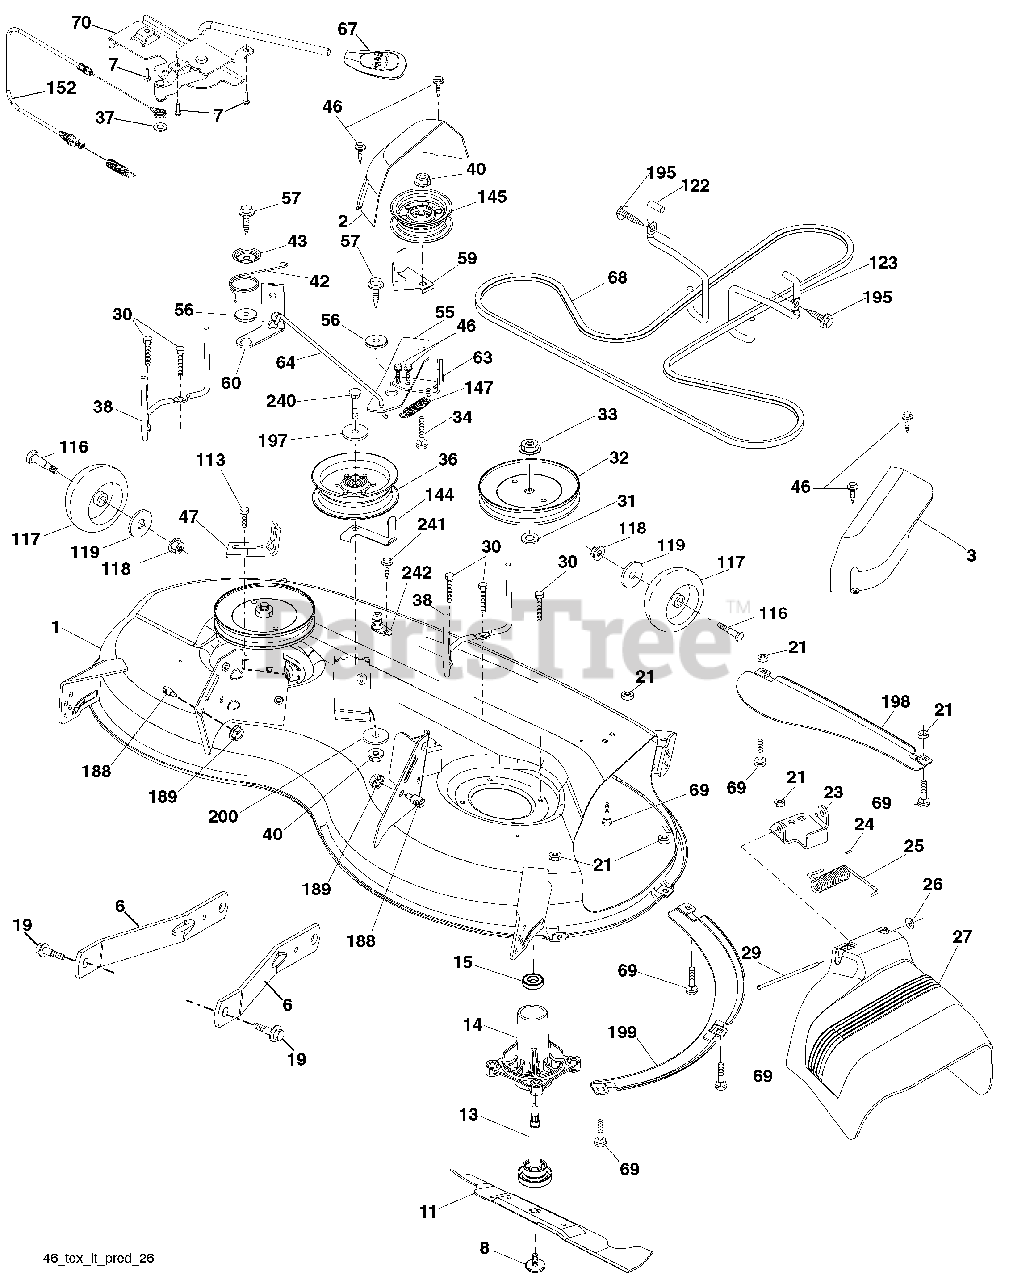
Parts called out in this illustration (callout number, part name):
1	Mower Housing
2	Cover Mandrel LH
3	Cover Mandrel RH
6	Arm Suspension
7	Screw #10 x 0.750 BOS Thread
8	Bolt/Washer Asm 7/16-20 unf
11	Blade Mower Hi-Lift
11	Blade Mower Mulching
13	Shaft Assembly, Mandrel
14	Housing, Mandrel
15	Bearing, Ball, Mandrel
19	Bolt, Shoulder
21	Nut
23	Bracket, Deflector
24	Cap, Sleeve
25	Spring, Torsion, Deflector
26	Nut, Push
27	Shield, Deflector
29	Rod, Hinge
30	Screw Thdrol Rolling Wsh Hd
31	Washer, Spacer
32	Pulley, Mandrel
33	Nut, Toplock, Flanged
34	Bolt Carr Sh. 3/8-16 x 1-1/2 Gr. 5
36	Pulley, Idler
37	Washer 13/32 x 13/16 x 16 Ga.
38	Keeper Belt LH Mandrel
40	Nut, Lock Flg. 3/8-16 unc
42	Spring Torsion Brake
43	Spring Torsion Retainer
46	Screw
47	Bracket Clutch Cable
55	Arm, Idler
56	Spacer, Retainer
57	Screw Hexwsh Thd 3/8-16 x 1
59	Guard, Tuv Idler (94)
60	Arm Brake Mower
63	Arm Brake Mower
64	Linkage Brake
67	Handle, Clutch Cable
68	V-Belt
69	Bolt
70	Clutch Asm. Manual
113	Screw 5/16-18
116	Bolt, Shoulder
117	Wheel, Gauge
118	Nut, Crownlock 3/8-1
119	Washer 13/32 x 7/8 x 14 Ga.
122	Keeper Belt Eng. LH
123	Keeper Belt Eng. RH
144	Keeper Belt
145	Pulley Idler Primary
147	Spring Return
152	Cable Clutch Manual w/Spr.
188	Stud Fastener
189	Nut Lock Hex Flange
195	Screw 3/8-16 x 3/4
197	Washer 13/32 x 13/16 x 12 Ga.
198	Baffle Center Front
199	Baffle Front RH
200	Washer 13/32 x 1 x 1/2 11 Ga.
240	Bolt Fin Hex 3/8-16 x 2-1/4 Gr. 5
241	Screw
242	Washout Port
242	Mandrel Assembly
242	Quick Connect Coupling
242	Replacement Mower, Complete
